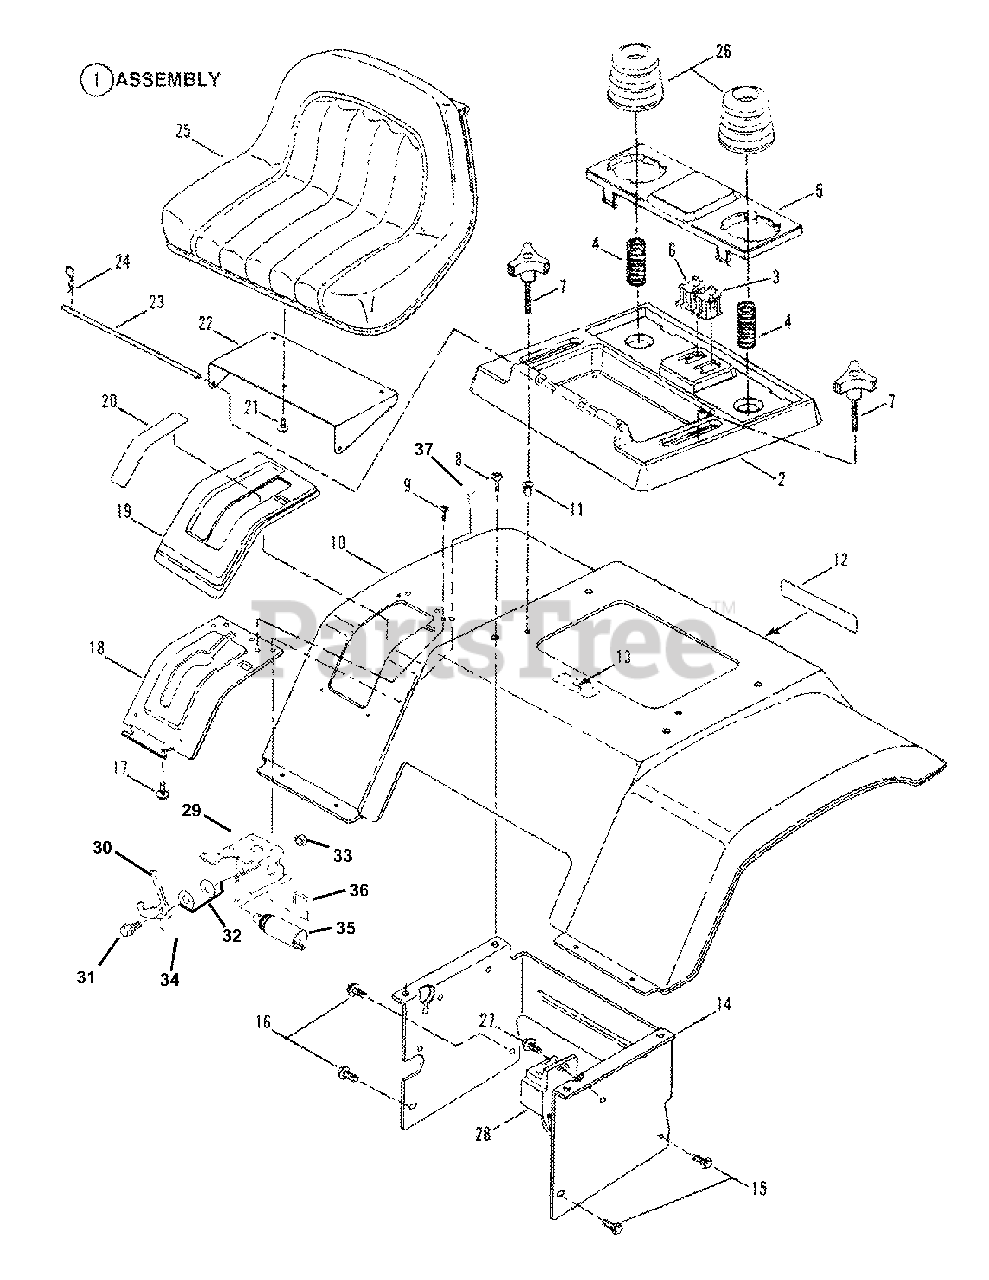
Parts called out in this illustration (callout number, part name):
1	ASSEMBLY, Seat Support
2	SUPPORT, Seat
3	SWITCH, Seat, Gray, (N.C.)
4	SPRING, Cushion Holder
5	HOLDER, Cushion
6	SWITCH, Seat
7	KNOB, Seat Adjustment, 5/16-18 x 2"
8	SCREW, 5/16-18 X 5/8" Truss Head Torx
9	SCREW, 1/4-20 x 5/8" Hex Washer Head, Self-Tapping
10	PAN, Seat (Fender)
11	RIV-NUT, 5/16-18 Round
12	DECAL - SNAPPER, 7.28" Molded Logo, Silver Letters & Blue Stripe
13	DECAL - CAUTION, Battery Location
14	SUPPORT, Fender
15	SCREW, 5/16/18 x 5/8" Hex Washer Head, Swage Form
17	SCREW, #10-16 x 1/2" Hex Washer Head, Self-Tapping
18	DETENT, Shift
19	COVER, Shift
20	DECAL, Shift Cover
21	BOLT, 5/16-18 x 1/2" Hex Flange Lock, Grade 5
22	BRACKET, Seat Support
23	ROD, Seat Hinge
24	PIN, 3/32 x 1-1/2" Hair
25	SEAT, Operator, V560
26	CUSHION, Seat
27	SCREW, #10-24 x 1/2" Hex Washer Self-Tap (Torx)
28	RECEPTACLE, Female Wire Harness Relay (Model: LT160H42GBV)
28	RECEPTACLE, Female Wire Harness Relay (Models: LT160H42GBV2 & LT180H48GBV2)
29	ASSEMBLY, Lockout Latch/Stop
30	OVERIDE, Latch
31	BOLT, 5/16-18 x 3/4" Shoulder
32	WASHER, 5/16 Flat
33	NUT, 5/16-18 Hex Top Lock
34	SPRING
35	SOLENOID, Electric
36	ROD, Connecting
37	SCREW, #10-24 x 1/2" Hex Washer Self-Tap (Torx)
